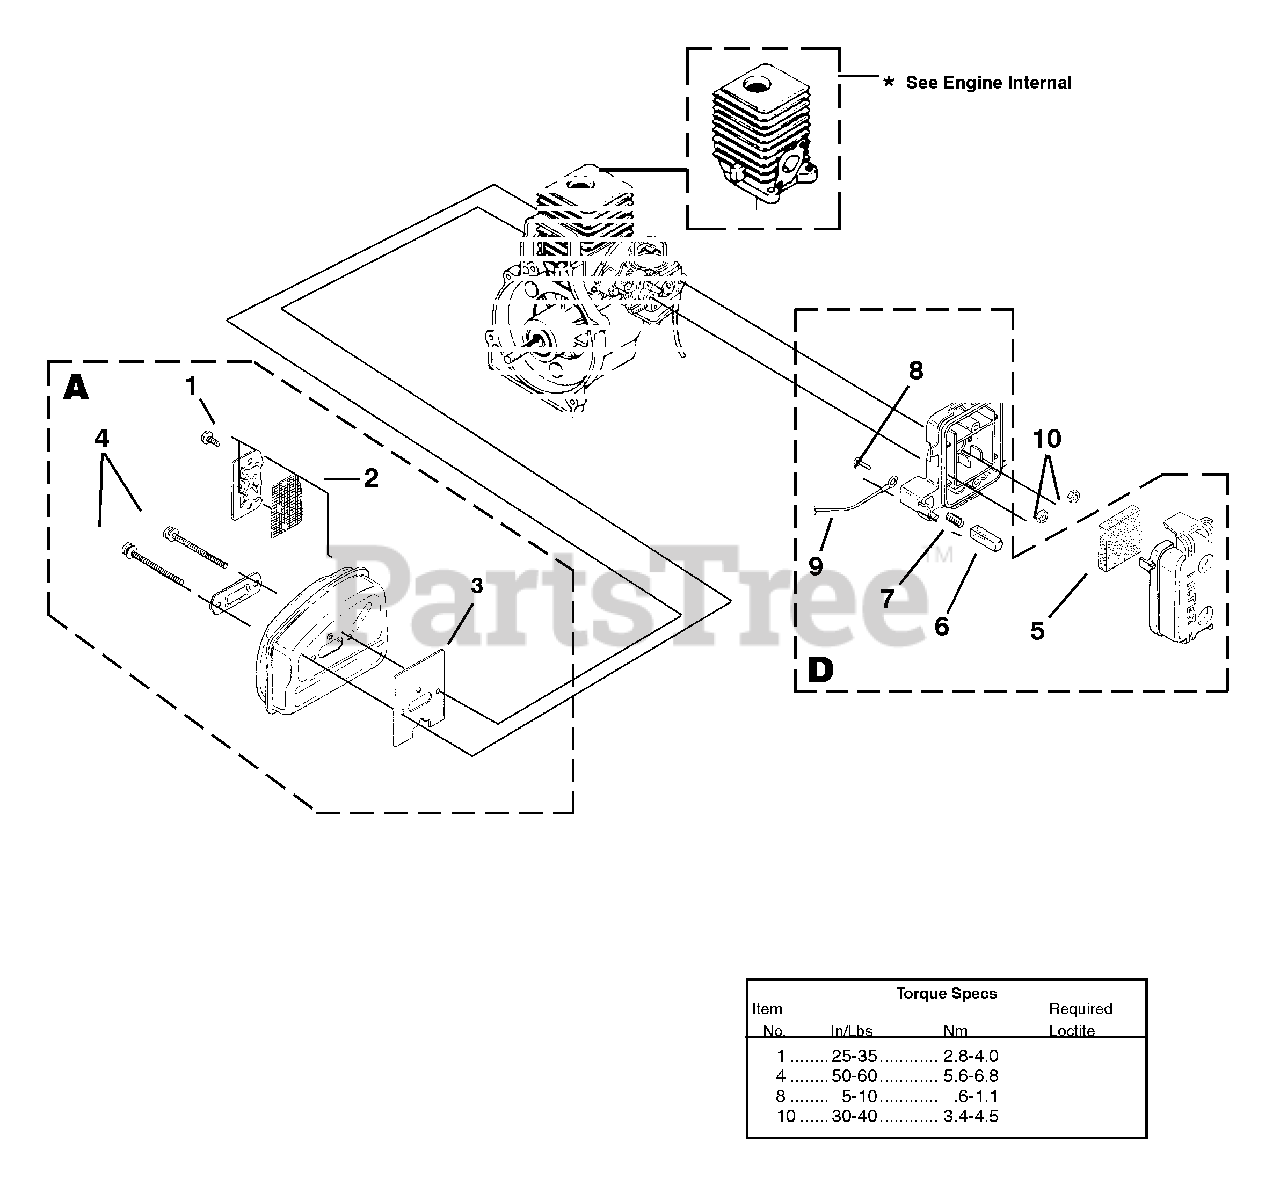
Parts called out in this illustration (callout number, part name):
1	SCREW, Taptite- (8-32 X 3/8")
2	SCREEN-Spark
3	GASKET-Muffler
4	SCREW, Truss Hd. - (10-24 X 2.188)
5	FILTER-Air
6	BUTTON-Switch
7	SPRING-Compression
8	SCREW-Thread Form (6-19 x 1/2")
9	LEAD-Electrical
10	NUT-Hex (10-24)
A	MUFFLER ASSY.
D	AIR FILTER KIT
